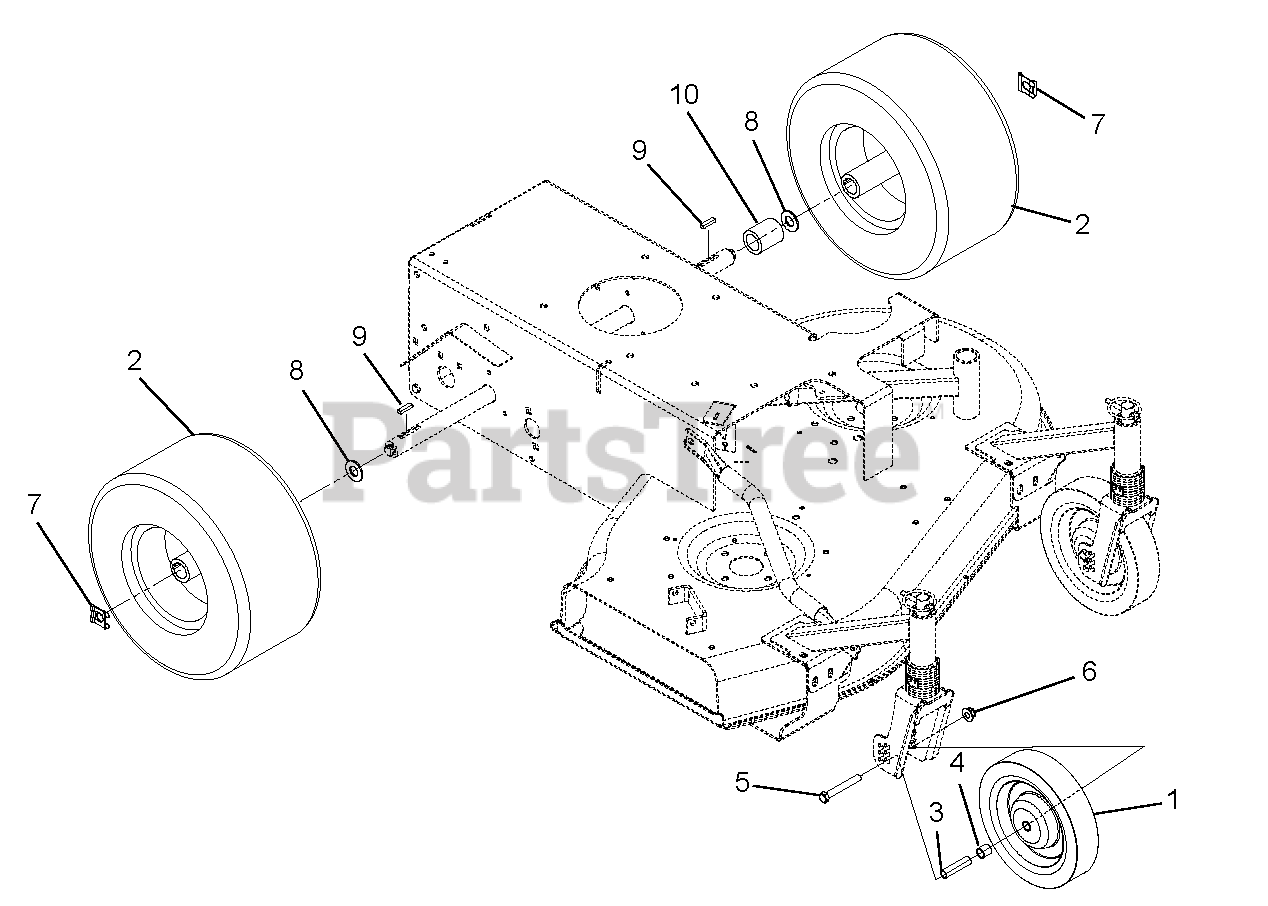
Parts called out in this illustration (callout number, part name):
1	Wheel, 8.0 x 1.75 x .50 - Ball Bearing
2	Assembly, Tire/Wheel 6 x 13
3	Spacer, Wheel
4	Spacer, Wheel
5	Bolt, Hex .38-16 x 2.75
6	Nut, Nyloc Flange .38-16
7	Clip, Snap .625 Diameter
8	Washer, Flat Steel .656 x 1.31 x .095
9	Key, Rectifier .25 x .188 x 1.00
10	Spacer 1.0 x 1.5 x 1.57
